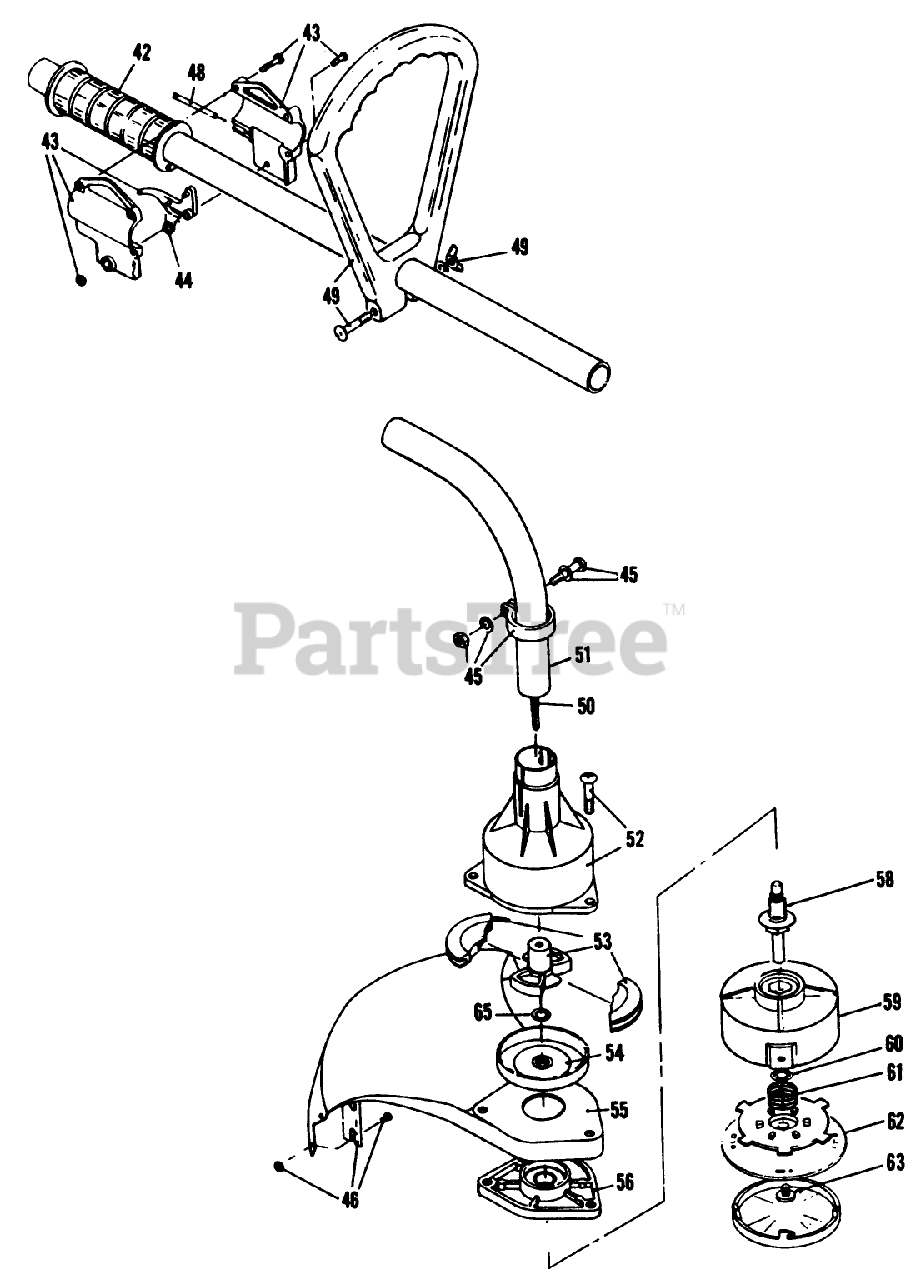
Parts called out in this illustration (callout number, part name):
42	Handle Grip
43	Trigger Assembly
44	Trigger Spring
45	Clamp Assembly
46	Blade (Discontinued)
48	Throttle Cable Assembly
49	Balance Handle Assembly
50	Flex. Drive Shaft
51	Tube Assembly
52	Clutch Housing
54	Clutch Drum
56	Bearing Housing Assembly
58	Drive Shaft
59	Spool Housing w/Eyelet
61	Actuator Spring
62	Cartridge Spool
63	Thumb Screw
